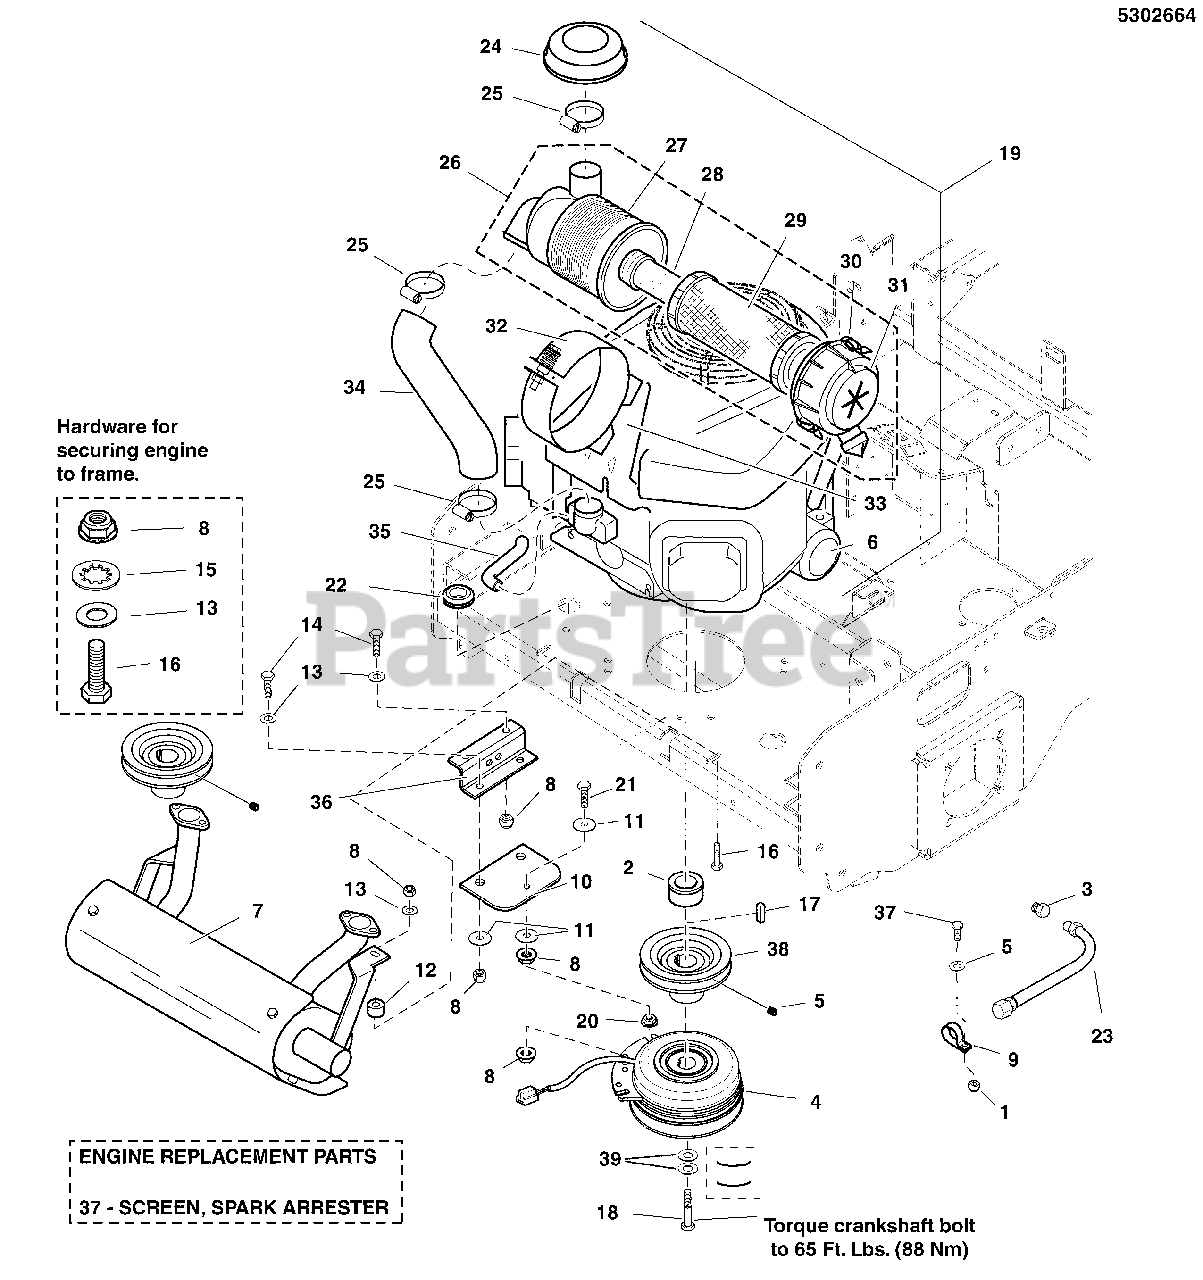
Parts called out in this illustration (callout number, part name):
1	NUT, 1/4-20, GR5 Flanged Nylock, Zinc/Clear
2	SPACER, 1.13 x 1.75 x 1.25
3	ADAPTER, Oil Drain
4	CLUTCH WARNER 200 FT-LB 1.13 X 6.323
5	SET SCREW, 5/16-18 X 3/8, KNURL, W/PATCH
6	FILTER,OIL,KAWA FS,FX,FR 603 & 726CC ENG (49065-7007)
7	MUFFLER, KAWI, HORIZONTAL, 5" CAN
8	NUT, 5/16-18 HEX NYLOCK FLANGE NUT
9	CLAMP, VINYL INSULATED, 1.00
10	CLUTCH ANCHOR PAD
11	WASHER, .34 X 1.25 X 10 GA
12	SPACER, .39 X 1.00 X .80, CZ
13	WASHER, 5/16" SAE
14	BOLT, 5/16-18 X 1" GRD5 YZ
15	WASHER, 5/16" Internal Tooth Lock
16	BOLT, 5/16-18 X 1-3/4" GD5 YZ
17	KEY, 1/4" SQ. X 1.00"
18	BOLT, CRANKSHAFT, 7/16 X 2-3/4, PATCH, CZ
19	* ENGINE, KAWASAKI
20	NUT, 5/16-18 HEX SERRATED FLANGE (SMALL)
21	BOLT, 5/16-18 X 2-1/4 TFL, GD5 YZ
22	GROMMET, 7/8"
23	HOSE, OIL DRAIN
24	RAIN CAP, AIR FILTER, 22,24&26HP, KAWASAKI (SV)
25	CLAMP, HOSE
26	CAP END, FILTER CASE
27	AIR FILTER ASSEMBLY, Complete
28	AIR FILTER, ELEMENT, SECONDARY
29	AIR FILTER, ELEMENT, PRIMARY
30	CLAMP, Cap
31	RUBBER, Dust Valve (SV)
32	CASE, BRACKET, COMPLETE
33	BRACKET PLATE
34	AIR INLET TUBE
35	BREATHER TUBE
36	ANCHOR, CLUTCH - BLK
38	PULLEY, 5.15 OD X 1-1/8 BORE B-SECT
39	BELLEVILLE WASHER, 1.1875 X .442 X .098
